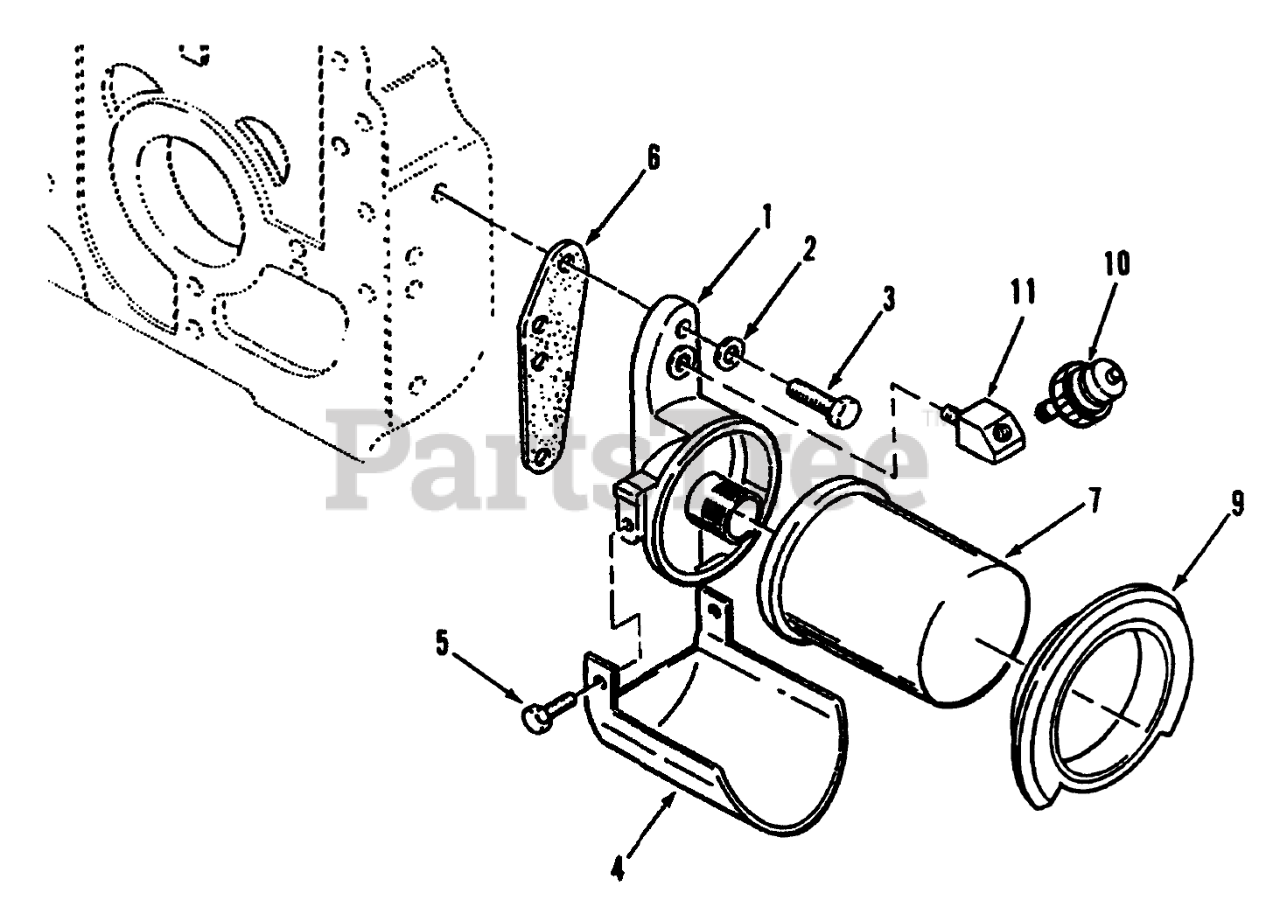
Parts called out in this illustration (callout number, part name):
1	ADAPTER-OIL FILTER
2	Washer
3	HHCS 5/16-18 X 1
4	OIL-FILTER DRAIN
5	SCREW-HH
6	Gasket
7	OIL FILTER
9	GASKET - AIR SEAL
10	SWITCH
11	45 DEG STREET ELBOW
